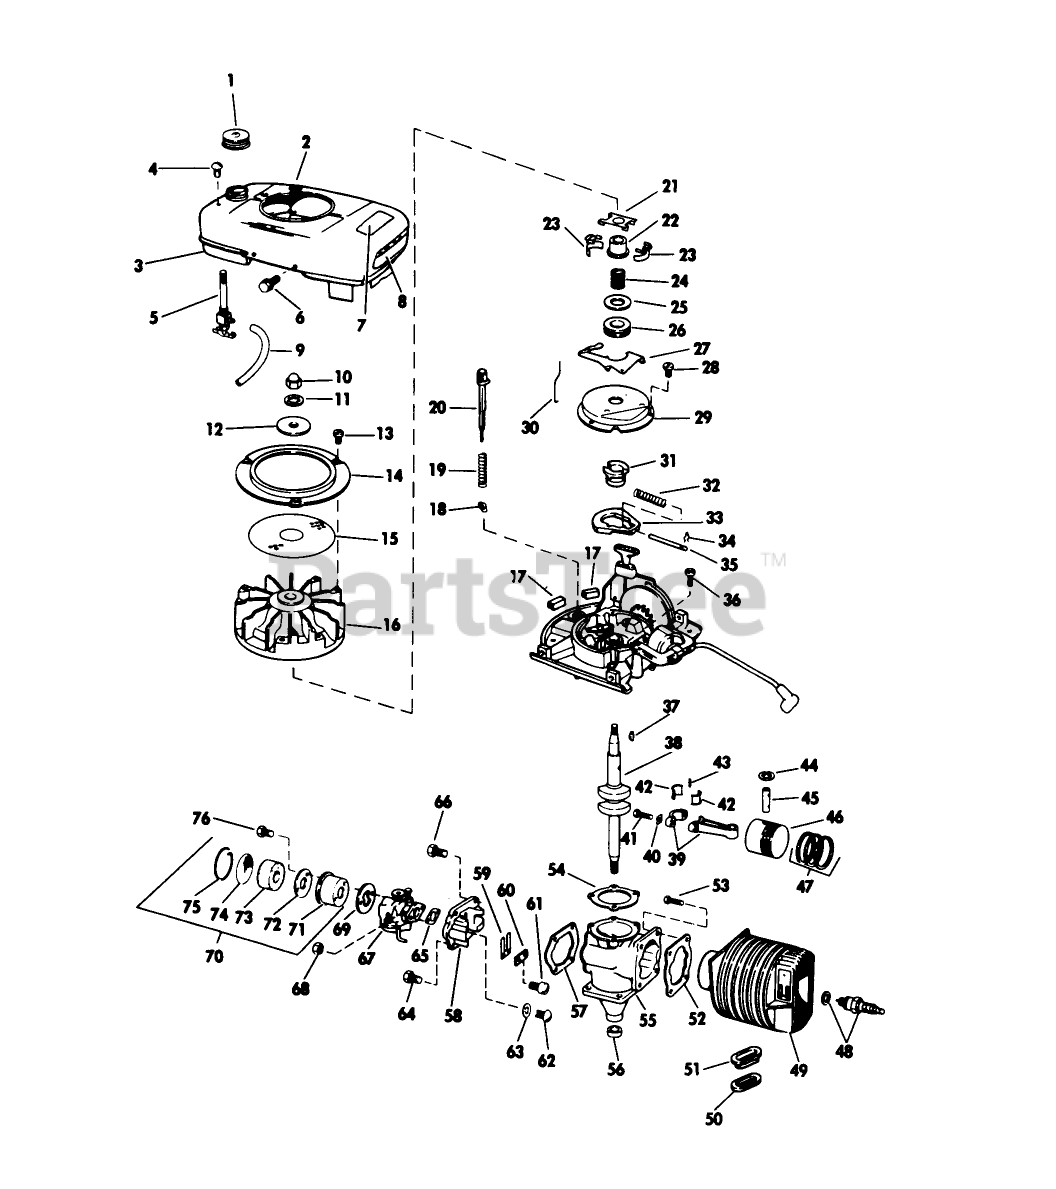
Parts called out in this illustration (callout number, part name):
5	VALVE&SCREEN SM
6	SCREW S
14	Ring-Flywhl. Scrn.
19	SPRING S
22	COLLAR S
26	THRUST COLLAR S
27	LEVER-GOVERNOR S
28	SCREW S
29	DUST COVER S
31	SPARK ADV. S
32	SPARK ADV. SPRING S
33	FLYWEIGHT S
34	SPARK ADJ. SPRING
35	PIN,SPARK ADV. S
42	LINER ASM
44	RING-RETAINING
48	Spark Plug
50	GASKET S
52	GASKET S
54	GASKET S
60	PLATE-BACKUP, REED
64	SCREW S
65	GASKET S
66	SCREW S
68	STOP NUT
72	BACK-UP PLATE
73	ELEMENT
76	SCREW S
